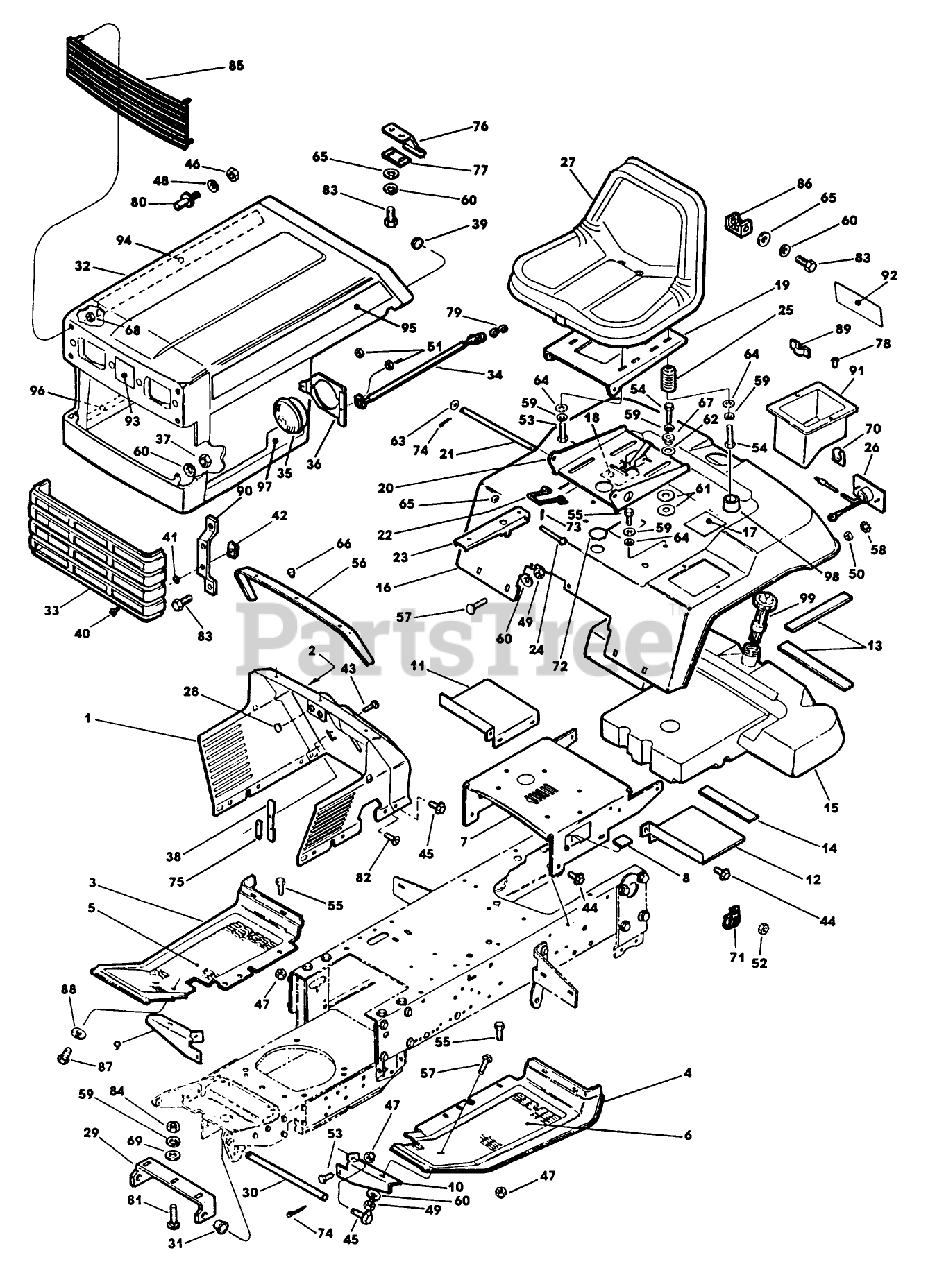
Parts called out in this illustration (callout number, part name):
14	PAD - FUEL TANK
15	TANK - FUEL
19	PIVOT AY - SEAT *B
20	SEAT SUPPORT AY
21	PIN
23	LATCH - SEAT PAN *B
24	PIN
26	TAILLIGHT
27	SEAT
30	ROD - HOOD PIVOT
31	BEARING-NYLINER
33	INSERT - GRILLE
37	NUT
40	FASTENER-1/4 TURN
47	NUT
49	NUT
53	SCREW - HEX
54	SCREW
61	WASHER-PLASTIC
63	WASHER
71	CLAMP - J EX
78	Rivet
80	PIN - CATCH
83	SCREW-HH
84	NUT SS
88	WASHER
95	DECAL - HOOD LH
98	CAP-PROTECTOR
99	GUAGE ASSEMBLY-FUE
